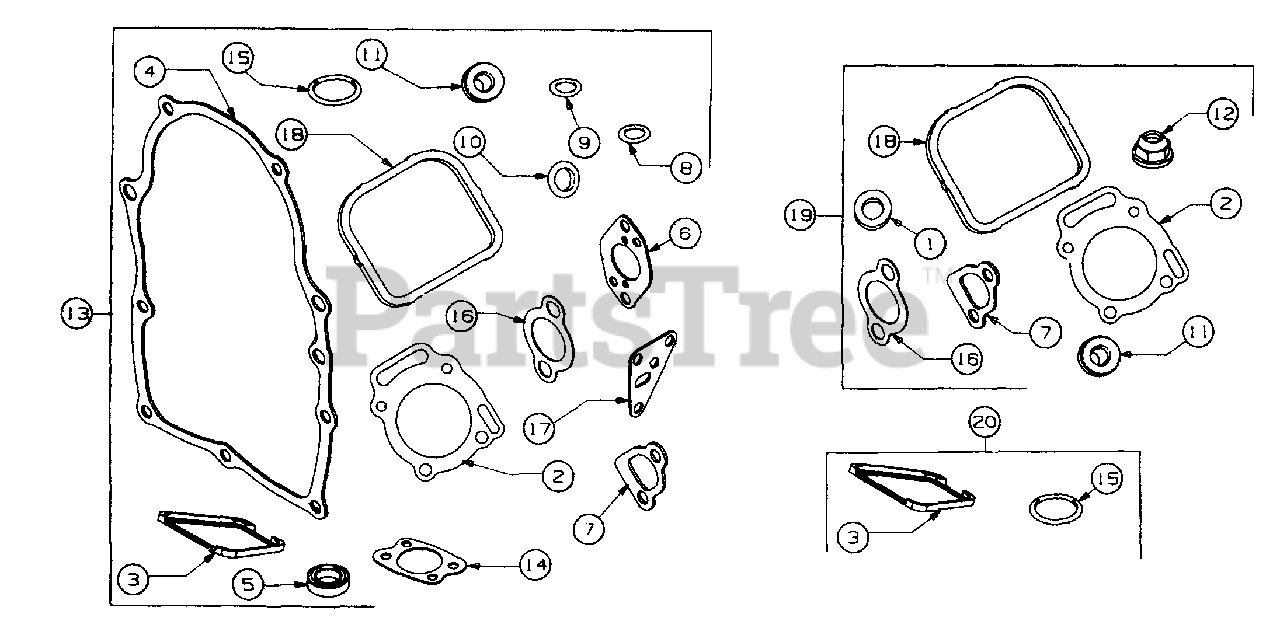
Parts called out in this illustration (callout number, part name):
1	Washer, Cylinder Head
2	Gasket, Cylinder Head
3	Gasket, Breather
4	Gasket, Crankcase Cover
5	Seal, Oil
6	Gasket, Carburetor Mtg
7	Gasket, Intake Manifold
8	O-Ring (Oil Pump)
9	O-Ring (Crankcase Cover)
10	Gasket, Sealing
11	Washer, Valve Cover
12	Nut, Nylock
13	Gasket Set
14	Gasket, Air Cleaner
15	Seal, Breather Screw
16	Gasket, Exhaust Manifold
17	Gasket, Oil Filter Adapter
18	Gasket, Valve Cover
19	Overhaul Kit, Valve
20	Gasket Set, Breather
